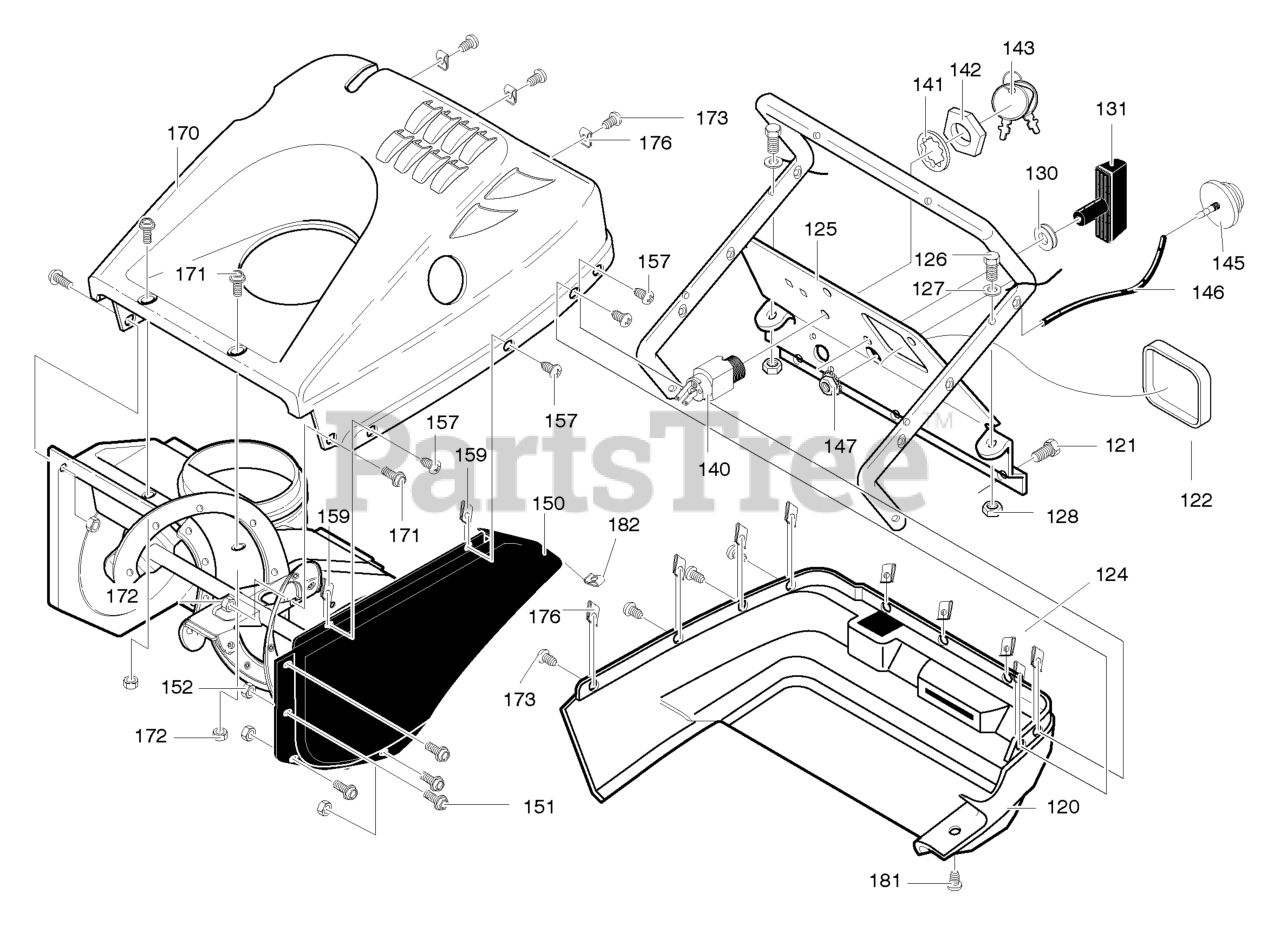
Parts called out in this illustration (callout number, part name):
120	COVER, BOTTOM
121	SCREW, 1/4-14X .75
122	PANEL, ACCESS
124	NUT, 1/4-10 SPEED
125	PANEL, CONTROL
126	SCREW, 1/4-20X1.25
127	WASHER, FLAT
128	NUT, 1/4-20
130	GROMMET
131	KNOB, STAND TEE
140	SWITCH, IGNITION
141	WASHER
142	NUT, 5/8-32
143	2 KEYS & RING
145	PRIMER BULB,
146	HOSE, PRIMER
147	NUT, 1/4-20
150	COVER, BELT
151	SCREW, 10-24X .50
152	NUT, #10-24
157	SCREW, 1/4-14X .75
159	NUT, 1/4-10 SPEED
170	COVER, TOP
171	SCREW, 10-24X .50
172	NUT, #10-24
173	SCREW, 1/4-14X .75
176	NUT, 1/4-10 SPEED
181	SCREW, 1/4-14X .75
182	NUT, 1/4-10 SPEED
